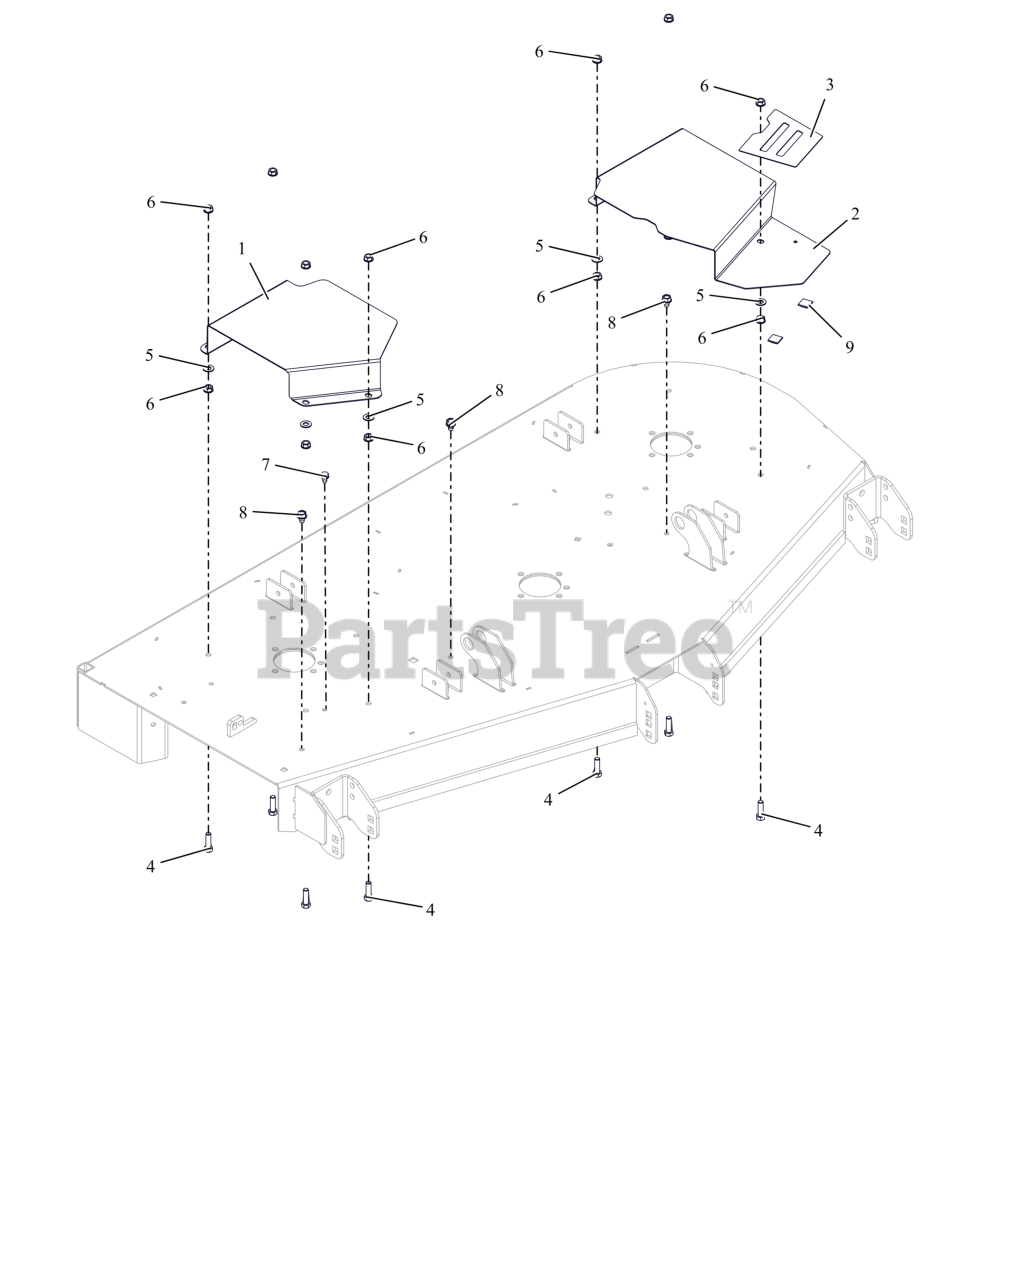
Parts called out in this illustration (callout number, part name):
1	COVER, BELT 52" & 60" RIGHT
2	COVER, BELT 60" LEFT
3	GRIP, TAPE 52-60 BELT COVER
4	BLT, HEX .38-16X1.25 G5 ZCC
5	WSHR,FLT .406X.812X.065 ZCC
6	NUT, SPNLK-FLG .38-16 G5 ZCC
7	SCR,TAP .312-18X.50 HWH TR ZCC
8	SCR,TAP .375-16X.50 HWH TR ZCC
